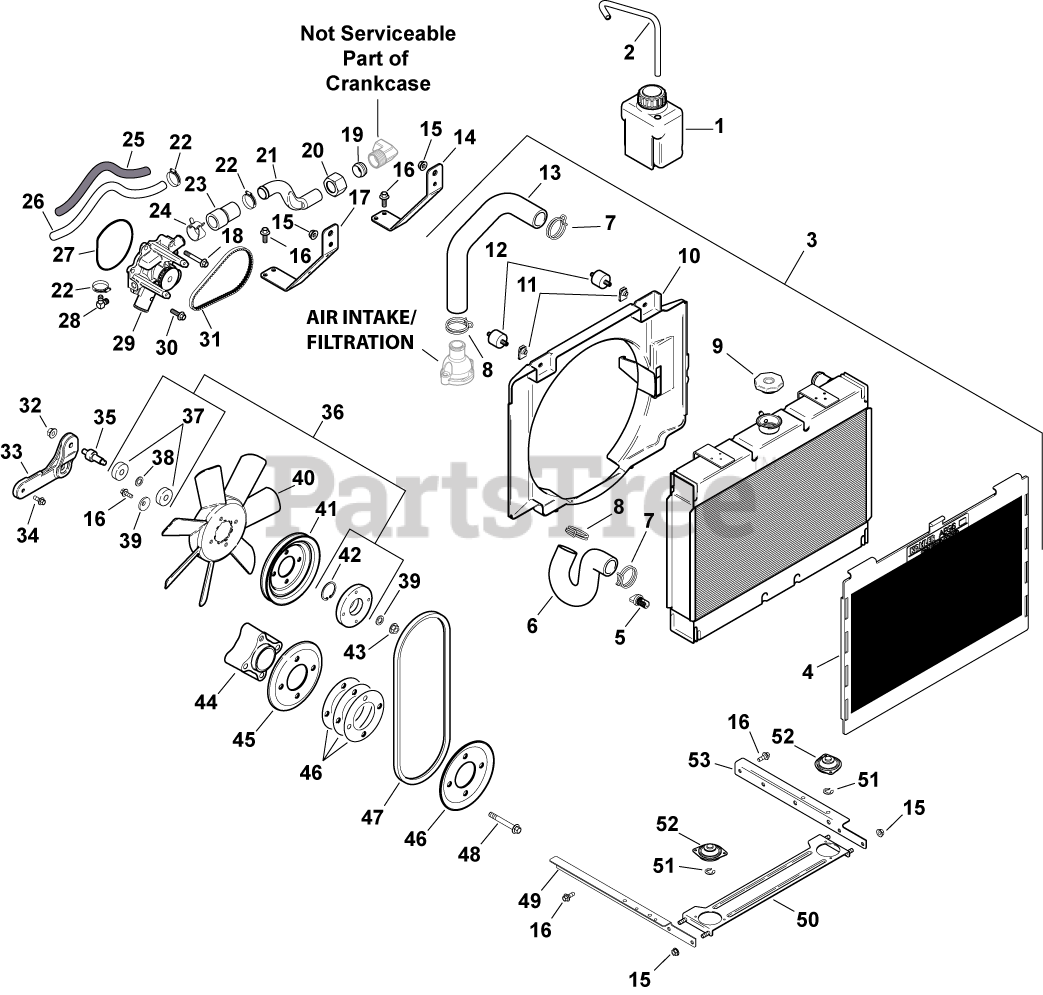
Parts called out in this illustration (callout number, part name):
1	BOTTLE, OVERFLOW
2	HOSE, OVERFLOW
4	SCREEN, GRASS (FLAT)
5	PLUG, DRAIN
6	HOSE, RADIATOR TO WATER PUMP (LOWER)
7	CLAMP, CONSTANT TENSION BAND
8	CLAMP, THERMOSTAT HSG OUTLET
9	CAP, RADIATOR - (#6617309S)
10	SHROUD, FAN
11	U CLIP - DISCONTINUED
12	MOUNT, ISOLATION
13	HOSE, THERMOSTAT TO RADIATOR (UPPER)
14	BRACKET,UP RADTR #1 SIDE-USE 66 126 75-S
15	NUT, FLG M6X1.0
16	SCREW, FLG M6X1.0X16
17	BRACKET,UP RADTR #2 SIDE-USE 66 126 78-S
18	SCREW, FLG M6X1.0X40
21	TUBE, CROSSOVER - USE 66 755 16-S
22	CLAMP, HOSE-USE 25 237 32-S
23	HOSE, CROSSOVER - USE 66 755 16-S
25	SLEEVE, INSULATING 14"
26	HOSE, BY-PASS 13"
28	CONNECTOR
29	PUMP ASSEMBLY, WATER - USE 66 393 10-S
30	SCREW, FLG M6x1.0x20
31	BELT, WATER PUMP
32	NUT, FLG M8X1.25
33	BRACKET, FAN
34	SCREW, FLG 8X1.25X16
35	SHAFT, FAN - USE 66 144 11-S
36	KIT, BEARING CARRIER
37	BEARING, BALL
39	WASHER, SPRING 1/4"
40	FAN, AXIAL PULLER
41	PULLEY, FAN
42	RING, RETAINER-INTL O.D. 30MM
43	NUT, FLG M8X1.25
44	ADAPTER, CRANKSHAFT PULLEY
45	PULLEY, CRANKSHAFT
46	SHIM, CRANKSHAFT PULLEY
47	BELT, FAN
48	SCREW, FLG M8X1.25X60
49	BRCKT KIT, LWR RADIATOR #2
50	BRACKET, RADIATOR CROSS
51	RETAINER, E-CLIP
52	MOUNT, PLATEFORM
53	BRCKT KIT, LWR RADIATOR #1
